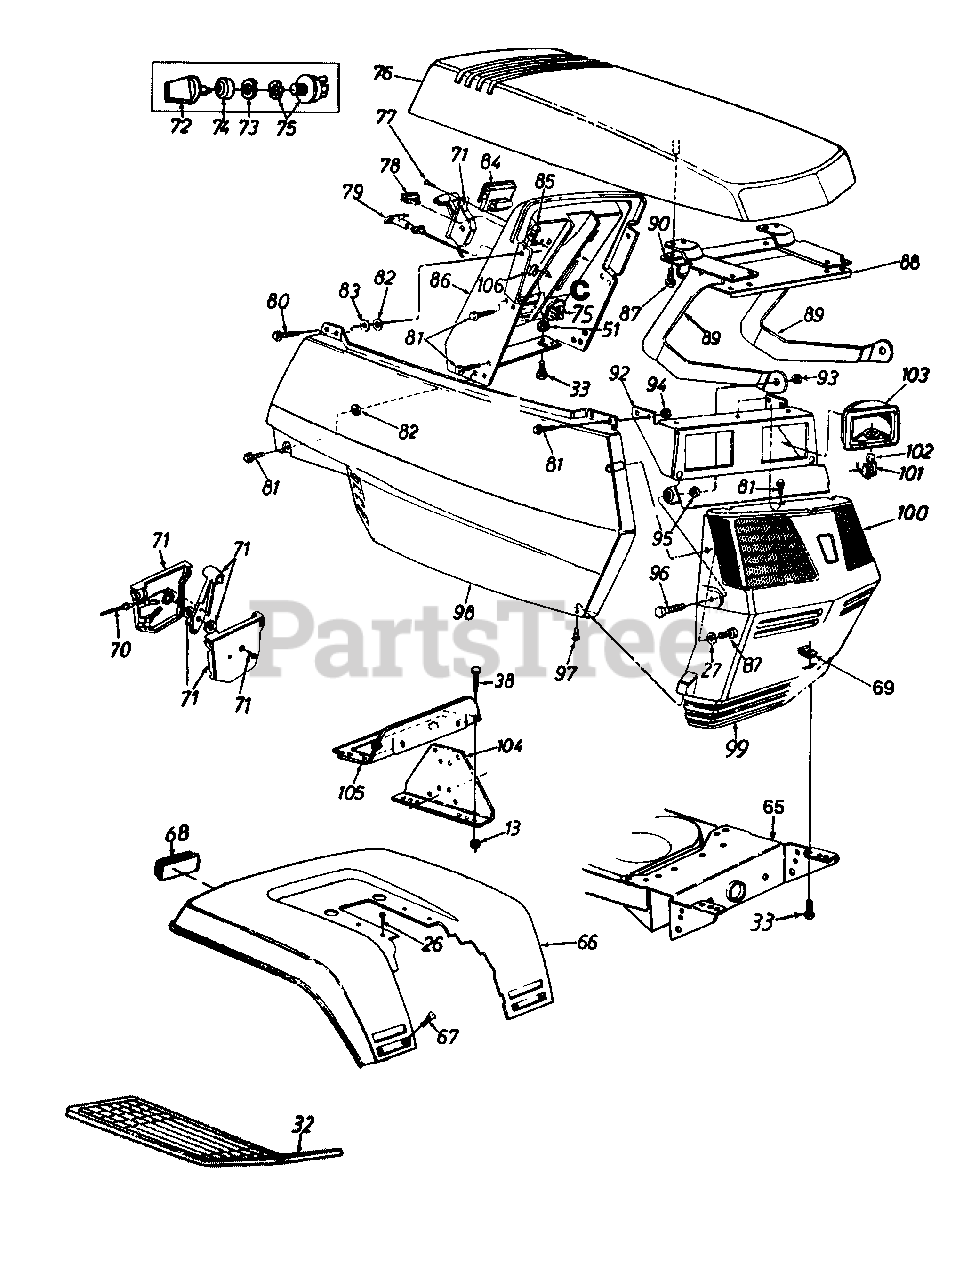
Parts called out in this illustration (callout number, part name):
13	Hex Sems Nut 1/4-20 Thd.
26	Hex Wash. Hd. AB-Tap Scr. 5/16 x .75" Lg.
27	Fl-Wash. .218" I.D. x .5" O.D.
32	Rubber Foot Pad - L.H.
33	Hex Bolt 5/16-18 x .75" Lg.
38	Hex Bolt 1/4-20 x .62" Lg.
51	Hex Sems Nut 5/16-18 Thd.
68	Reflector
69	U-Nut 5/16-18 Thd.
70	Throttle Wire 18.5" Lg.
71	Throttle Control Box Ass'y.
72	Ignition Key
73	Ignition Switch Nut
74	Ignition Switch Cap
75	Ignition Switch
76	Hood
77	Truss Mach. AB-Tap Scr. #10 x .5" Lg.
78	Light Switch
79	Choke Control (Single Cylinder and Kohler Engine)
80	Hex Wash Hd Tap Scr 1/4 x .75" Lg.
81	Hex Tap Scr 1/4-20 x .5" Lg.
82	Push Nut Fastener
83	Fl-Wash. 27" I.D. x .948"
84	Ammeter
85	Speed Nut 1/4-20 Thd.
86	Dash Panel
87	Hex Wash. Hd. B-Tap Scr. 1/4 x .75" Lg
94	Hex L-Nut 1/4-20 Thd.
95	Hex Jam Nut 5/16-18 Thd.
96	Hex Bolt 5/16-18 x 7/8" Lg
97	Truss Mach. B-Tap Scr #10 x 5" Lg.
98	Side Cover - R.H
99	Grille
100	Lens - L.H
101	Twist Lock - Lamp Socket
102	Lamp
103	Headlight Housing
